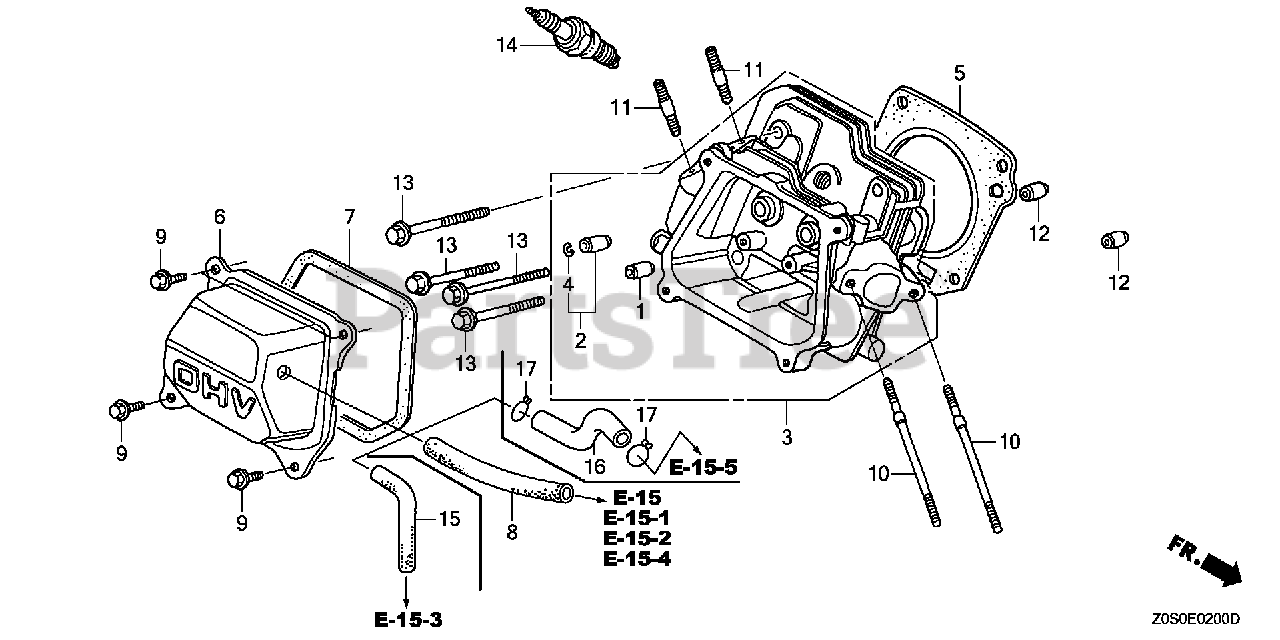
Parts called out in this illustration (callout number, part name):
3	CYLINDER HEAD
4	CLIP, VALVE GUIDE Use from Engine SN 1231803.
5	GASKET, CYLINDER HEAD
6	COVER, HEAD
7	GASKET, CYLINDER HEAD COVER
7	GASKET, HEAD COVER
8	TUBE, BREATHER
9	BOLT, FLANGE (6X12) (CT200)
10	BOLT, STUD (6X114)
11	BOLT, STUD (8X32)
12	PIN A, DOWEL (10X16)
13	BOLT, FLANGE (8X55)
14	SPARK PLUG (BPR5ES) (NGK)
14	SPARK PLUG (BPR6ES) (NGK)
14	SPARK PLUG (W16EPR-U) (DENSO)
14	SPARK PLUG (W20EPR-U) (DENSO)
